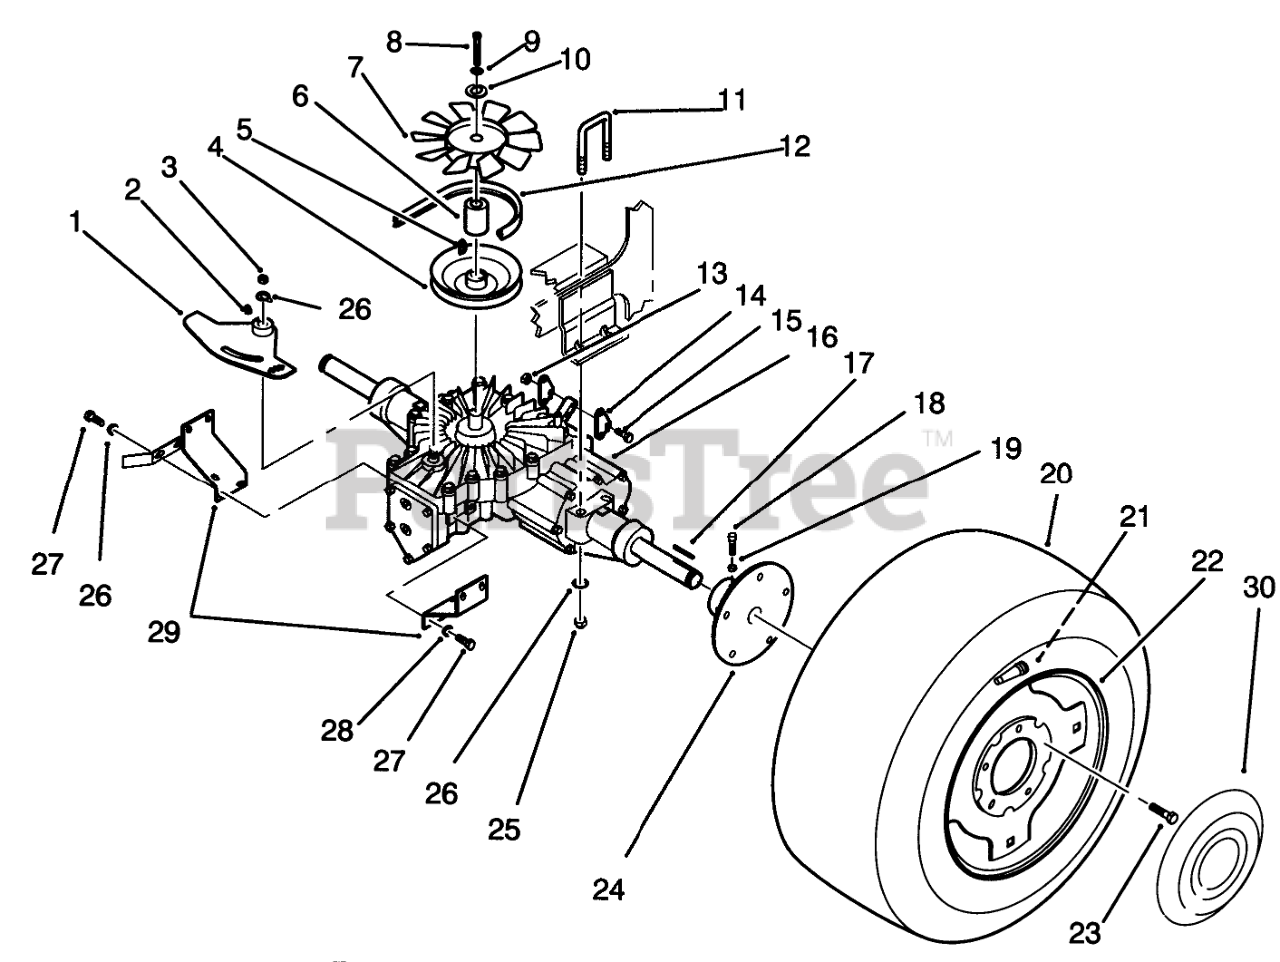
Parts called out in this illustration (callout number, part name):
1	WLDMT-CONTROL ARM
2	KEY WOODR 1/8X1/2 DI
3	PINION SHAFT
4	PULLEY-TRANS
5	HARD HI PRO KEY
6	SPACER
7	FAN-7"
8	Screw
9	WASHER-LOCK
10	WASHER
11	U-BOLT
12	BELT-V
13	NUT-LOCK, NI
14	BRACKET
15	SCREW-HH
16	751-TRANSAXLE
17	KEY-SQUARE
18	Screw-Set
19	NUT-JAM
20	TIRE
21	VALVE
22	WHEEL
23	BOLT-LUG
24	Hub-Rear
25	NUT-LOCK, NI
26	WASHER-FLAT
27	SCREW-HH
28	WASHER-FLAT
29	BRACKET R
30	12"-HUB CAP LOGO
